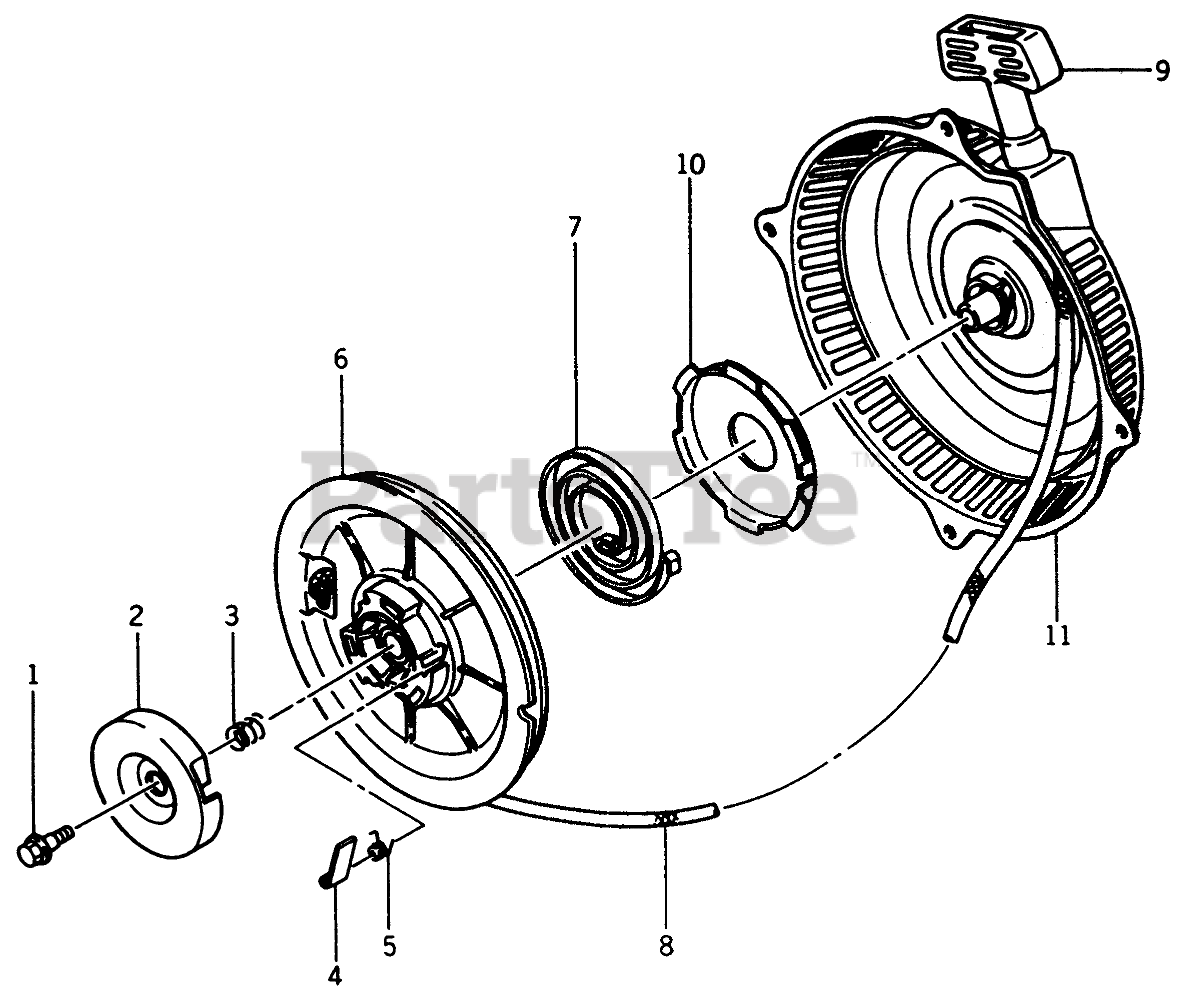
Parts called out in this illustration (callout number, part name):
1	Bolt
3	Return Spring
4	Pawl
5	Spring-RETURN
9	Grip
